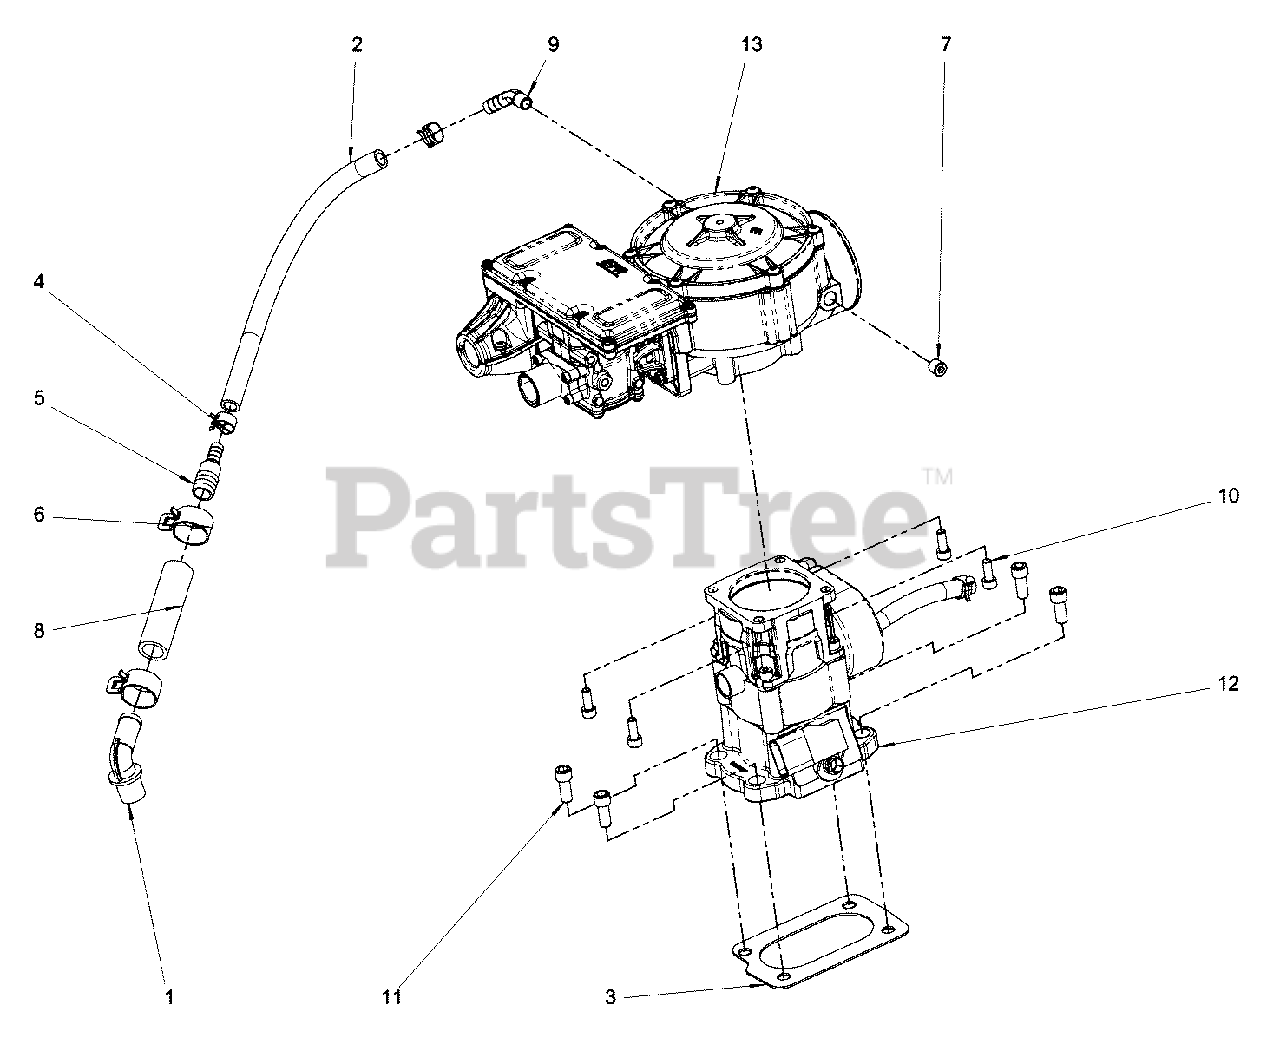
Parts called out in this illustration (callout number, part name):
2	HOSE, FUEL, 14"
3	GASKET, ADAPTER
7	PLUG
8	HOSE, VAPOR, 3"
9	FITTING
10	BOLT
11	BOLT
